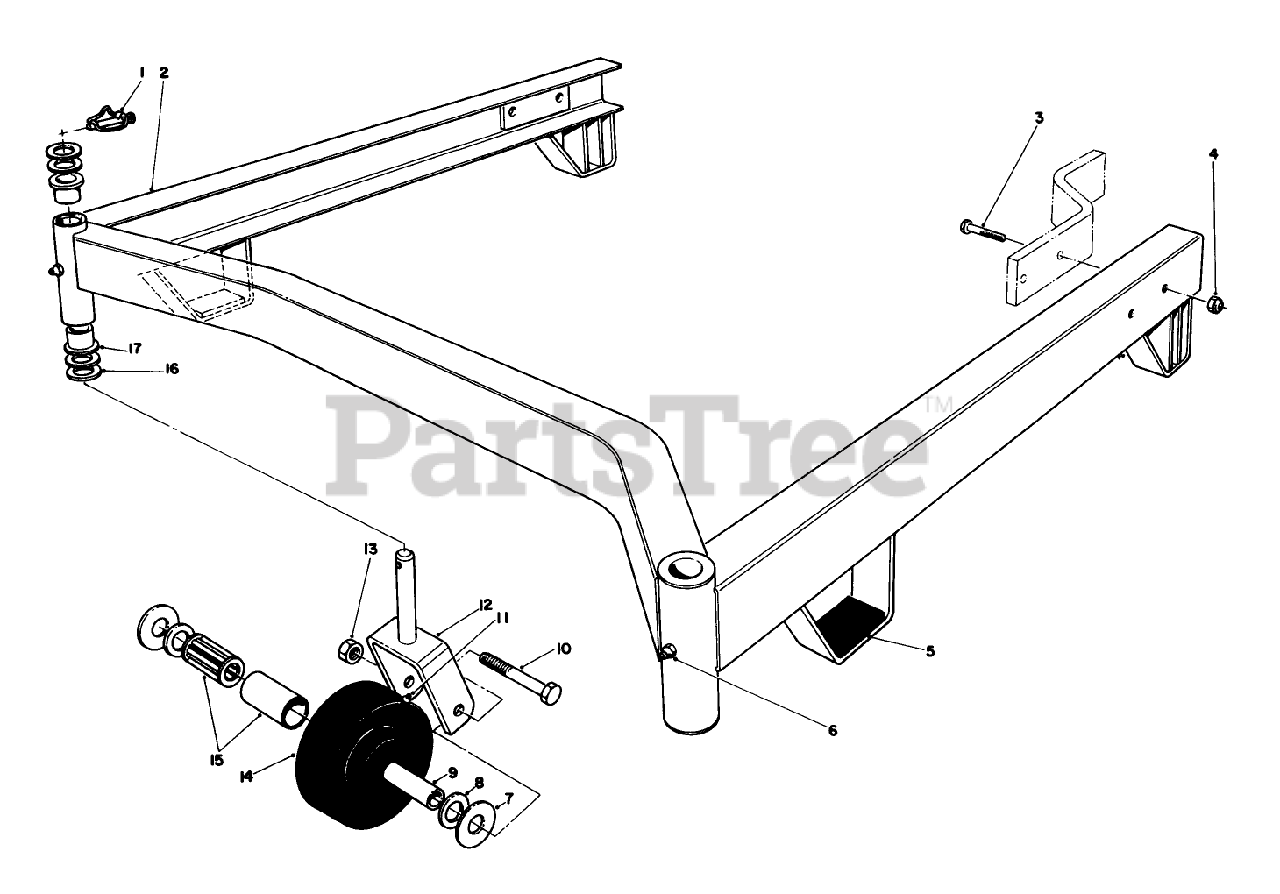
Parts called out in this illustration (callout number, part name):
1	PIN-LYNCH
3	SCREW-HH
4	NUT-LOCK, CONE
6	FITTING-GREASE
7	THRUST WASHER
8	BEARING RETAINER
9	SPANNER BUSHING
10	SCREW-HH
11	FITTING-GREASE
13	NUT-LOCK
14	WHEEL
15	ROLLER BEARING
16	WASHER-THRUST
